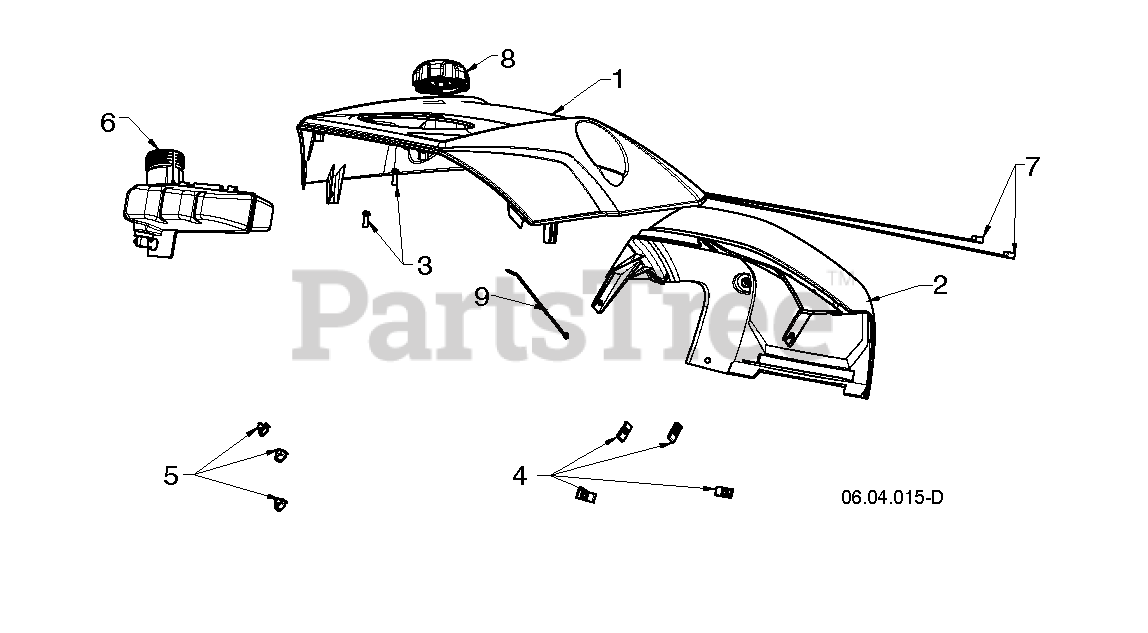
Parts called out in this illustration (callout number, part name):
1	COVER.TOP.SSST.ORANGE
2	COVER.REAR.UPPER.GREY
3	SCREW.HX.13X.750
6	RP_TANK.GAS.12.SINGLE.STAGE.SN
7	TIE.CABLE.24.5X.29.NYLON.WHITE
8	CAP.2.25'.VENTED.RATCHET.EPA
9	WIRE.TIE
